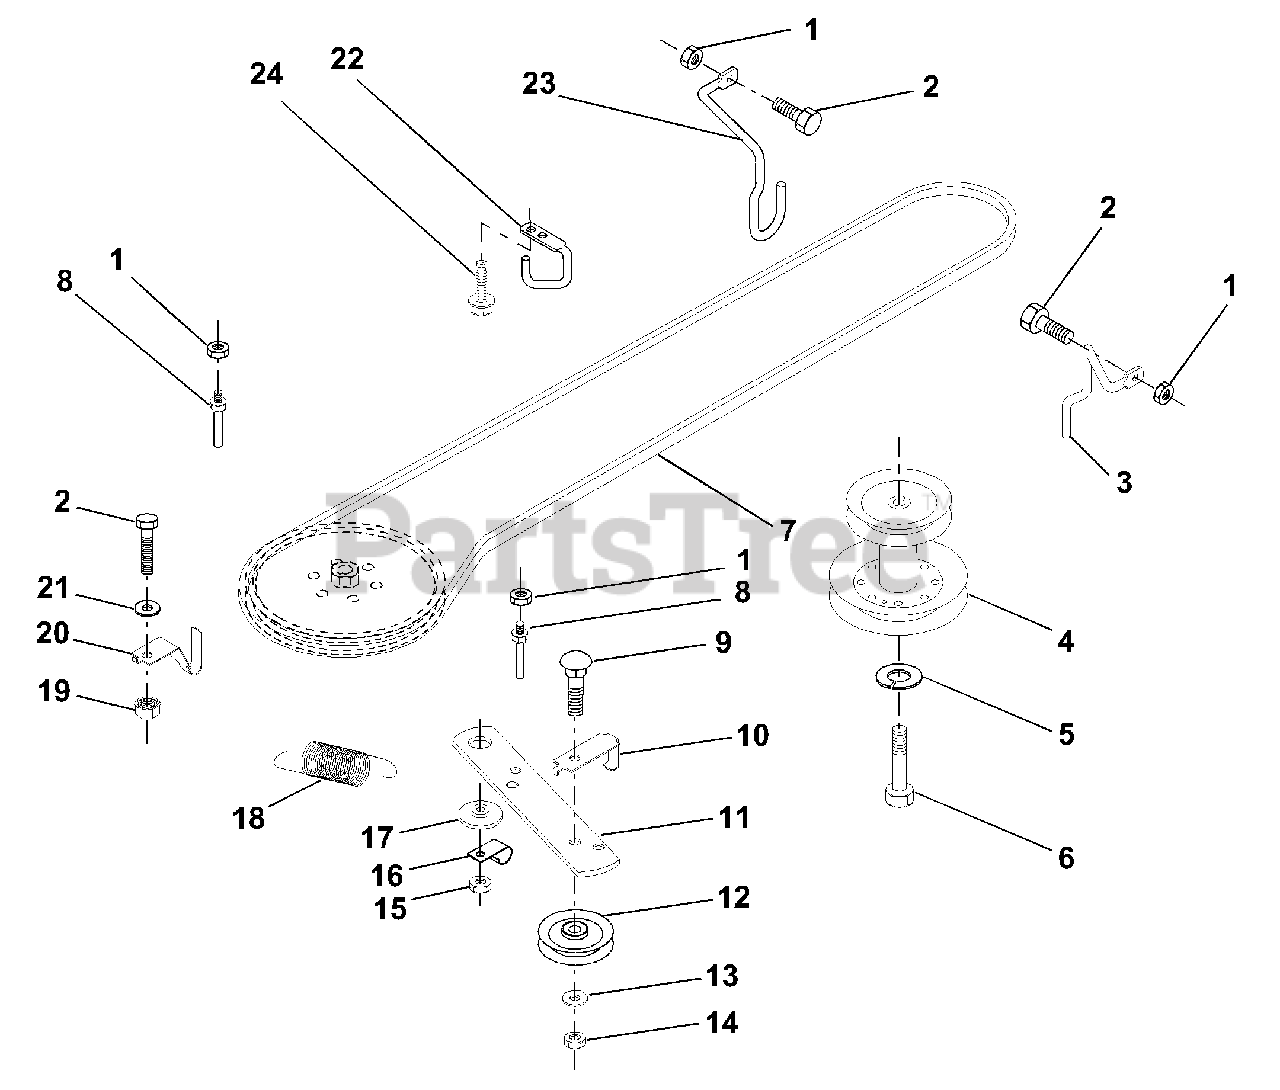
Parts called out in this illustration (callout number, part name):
1	Nut, Crownlock 5/16-18
2	Bolt, Hex Hd 5/16-18 UNC x 3/4
3	Keeper,Mower Drive, R. H.
4	Pulley, Engine
5	Washer, Lock 7/16
6	Bolt Hex 7/16-20 Gr. 5
7	Traction, V-Belt Drive
8	Keeper, T/A Ground Drive Belt
9	Bolt, Carr. 3/8-16 UNC x 1-1/2
10	Keeper, Belt Ground Drive Idler
11	Arm, Ground Drive Clutch
12	Idler, Flat
13	Washer 13/32 x 13/16 x 16 Ga.
14	Nut, Centerlock 3/8-16 UNC
15	Nut, Crownlock 3/8-16 UNC
16	Clip, Insulated
17	Spacer, Retainer
18	Spring Extension
19	Nut, Keps 5/16-18 UNC
20	Keeper, T/A Ground Drive Belt
21	Washer 11/32 x 5/8 x 16 Ga.
22	Keeper, Frame Ground Drive Belt
23	Keeper, Mower Drive, L. H.
24	Screw
